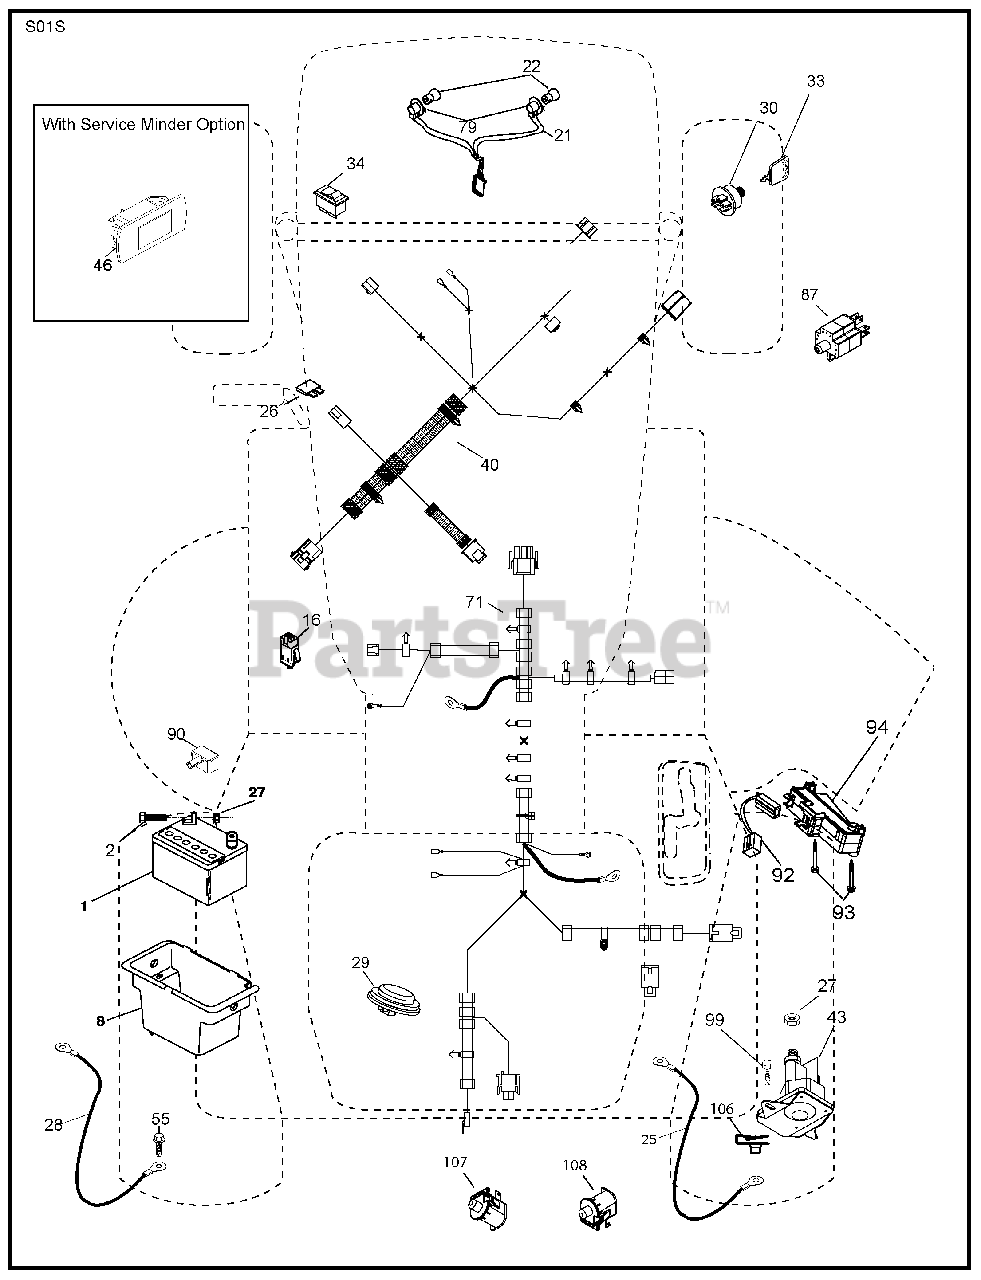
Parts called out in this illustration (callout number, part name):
1	Battery
2	Bolt Hex Head 1/4-20 x 3/4
8	Box Battery
16	Switch Interlock Push-In
21	Harness Socket Light w/4152J
22	Bulb Light
25	Cable Starter
27	Nut Keps Hex 1/4-20 unc
28	Cable, Ground
29	Switch, Seat
30	Switch, Ign
34	Switch Light/Reset
40	Harness Ign. Dash
43	Solenoid
55	Screw Thdrol 5/16-18 x 3/4 TYTT
71	Harness Ign. Chassis
79	Socket Asm. Bulb
87	Switch Railmount NO-NC-NC
90	Cover Terminal
92	Harness Pigtail Console ROS
93	Screw Plastite 14 X 6
94	Module Reverse ROS
99	Screw 1/4-20 x 3/4
106	Palnut 1/4 Lugs
107	Switch Snapmount No #2
108	Switch Snapmount NC
